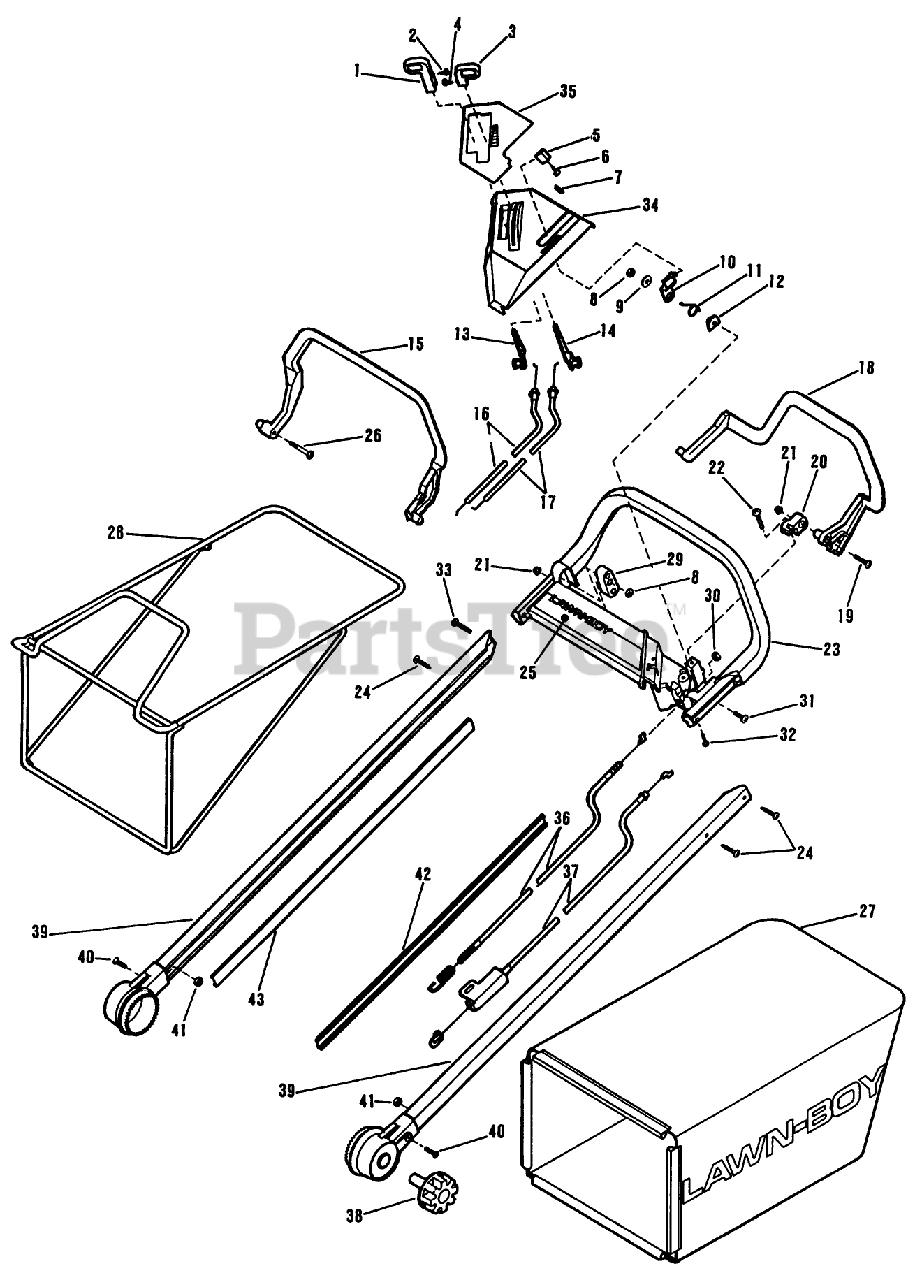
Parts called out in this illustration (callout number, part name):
1	KNOB & SCREW AY
8	LOCKNUT E
10	BBC LATCH LB
11	SPRING
16	CABLE AY. WESCON
17	CABLE
18	BAIL-S.P. *
20	PIVOT BAIL PL
21	LOCKNUT FLAN
24	SCREW
27	REPL BAG FOR 684190
29	BLOCK BAIL PL
31	SCREW-CROSS RECESS
33	SCREW-TRUSS
37	CABLE AY WESC
38	KNOB-HDLE MT.ASM*B
41	LOCKNUT FLAN
